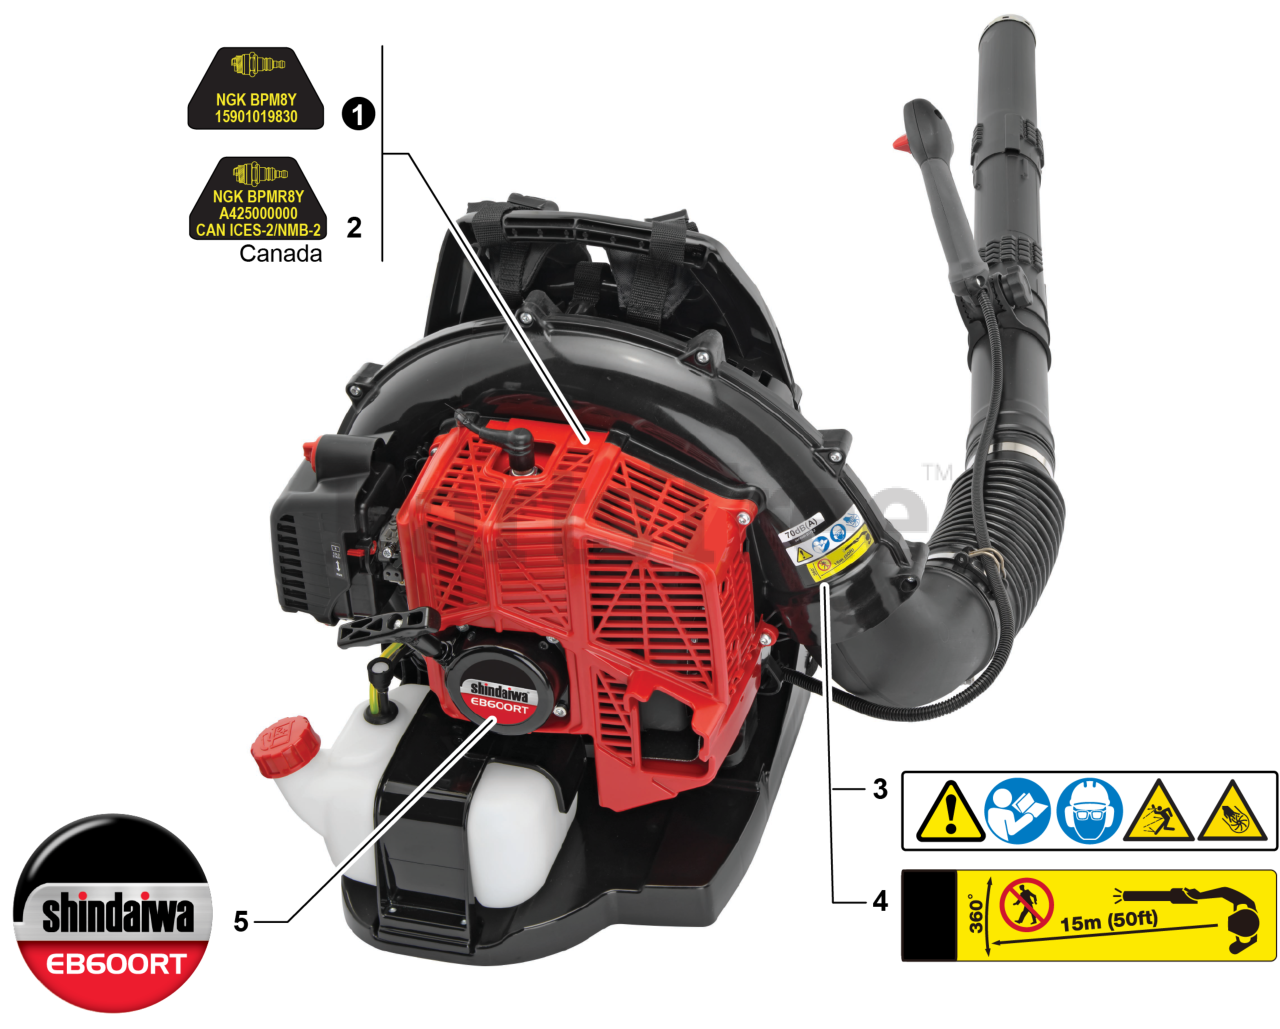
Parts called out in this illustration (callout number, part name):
1	LABEL - SPARK PLUG - BPM8Y
2	LABEL - SPARK PLUG - BPMR8Y
3	LABEL - CAUTION - ISO
4	LABEL - CAUTION - BLOWER
5	LABEL - MODEL EB600RT
